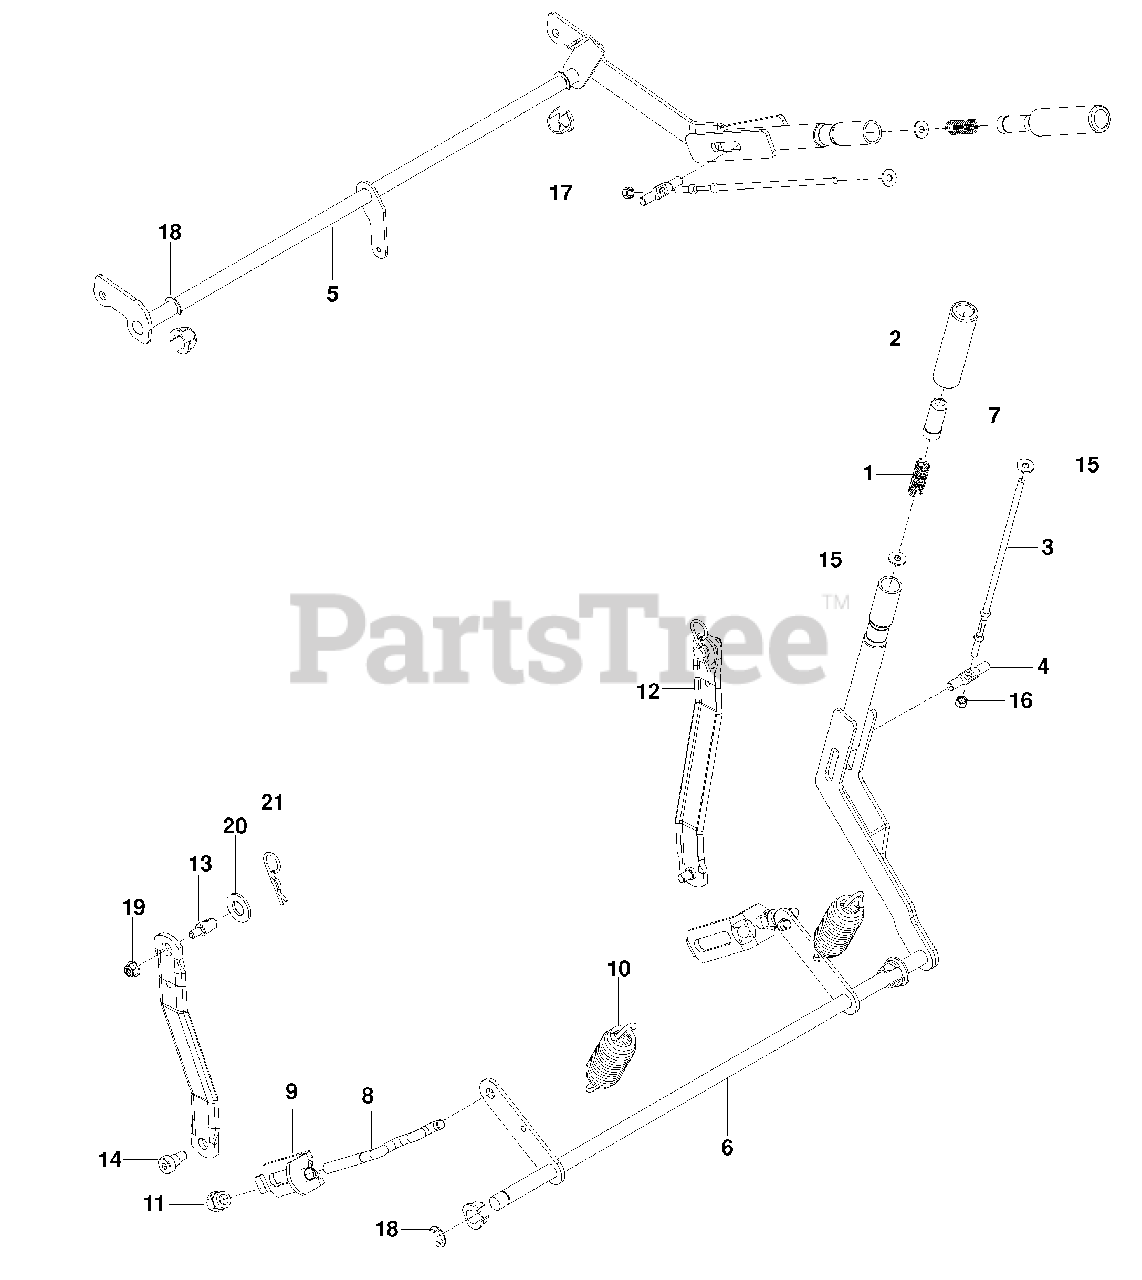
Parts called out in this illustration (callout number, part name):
1	Spring, Compression
2	Grip, Handle
3	Rod, Handle Release
4	Rod, Latch Release
5	Shaft, Brake
6	Shaft, Lift
7	Button, Push
8	Link, Rear Suspension
9	Bracket, Centering Lnk
11	Nut, Lift Link
12	Arm, Suspension Rr
13	Stud, W/Anti- Rotate
14	Bolt 3/8-16 X 3/8 Skt Hd
15	Washer 1/4 Flat
16	Nut 1/4-20 Hex Nyloc
17	Plastic Nut
19	Nut 5/16-18 Flange Nyloc
20	Washer 5/8 Sae
21	Hairpin #4
